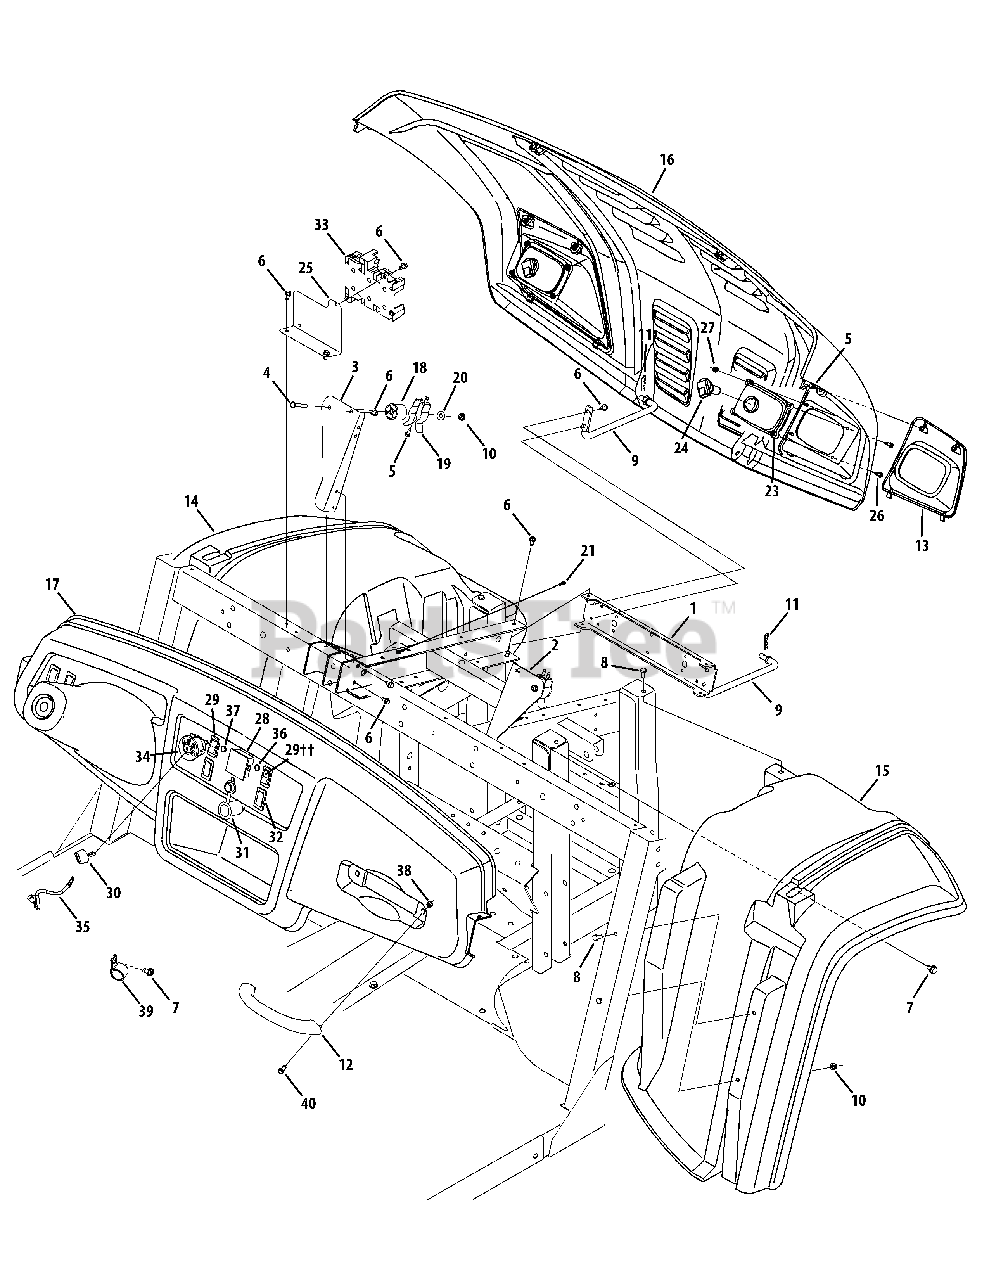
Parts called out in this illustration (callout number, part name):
4	Screw, 1/4-20, 1.75, Gr5, Std
5	Screw, #12-16 x .50
6	Screw, TT, 1/4-20 x .500
7	Screw, TT, 5/16-18 x .500
8	Screw, 1/4-20, .75, Gr5, Std
9	Rod, Mt, Hood
10	Nut, Flange Lock, 1/4-20
11	Pin, Cot, Int .08 X 1.42
12	Hndl, Bag, W/scr 400/500 S
13	Bzl, Hdlt RH
13	Bzl, Hdlt LH
14	Fdr, Lh 4x4
14	Fdr, Lh 4x4, Camo
15	Fdr, Rh 4x4
15	Fdr, Rh 4x4, Camo
16	Hood, 4x4, Camo
16	Hood, 4x4, Camo, Tracker
16	Hood, 4x4, Green
17	Dash, Uv 4x4
18	Rlr, Latch, Hood
19	Spr, Latch, Hood
20	Wash, Fl, .283 X .75 X .030
23	Headlight Assembly (Incl. # 24)
24	Headlamp Bulb
26	Screw, TT, #10-24 x .750
27	Nut, Hex Lock, #10-24
28	Meter, Ind., Hour Flat Face
29	Switch, 4x4, Rocker
30	Key, Delta, Plastic
31	Recptl, Pwr, 12v
32	Pnl, Plug, Switch
33	Relay, Hldr, 3-Way
34	Switch, Key, 4 Pos. Delta
35	Engine Ground Wire
36	Lgt., Ind., Red, LED
36	Lamp, Ind., Red, Incandescent
37	Lgt., Ind., Yellow, LED
37	Lamp, Ind., Green, Incandescent
38	Nut, Hexlk., 1/4-20
40	Scr., Mach., 1/4-20 x 1.00
